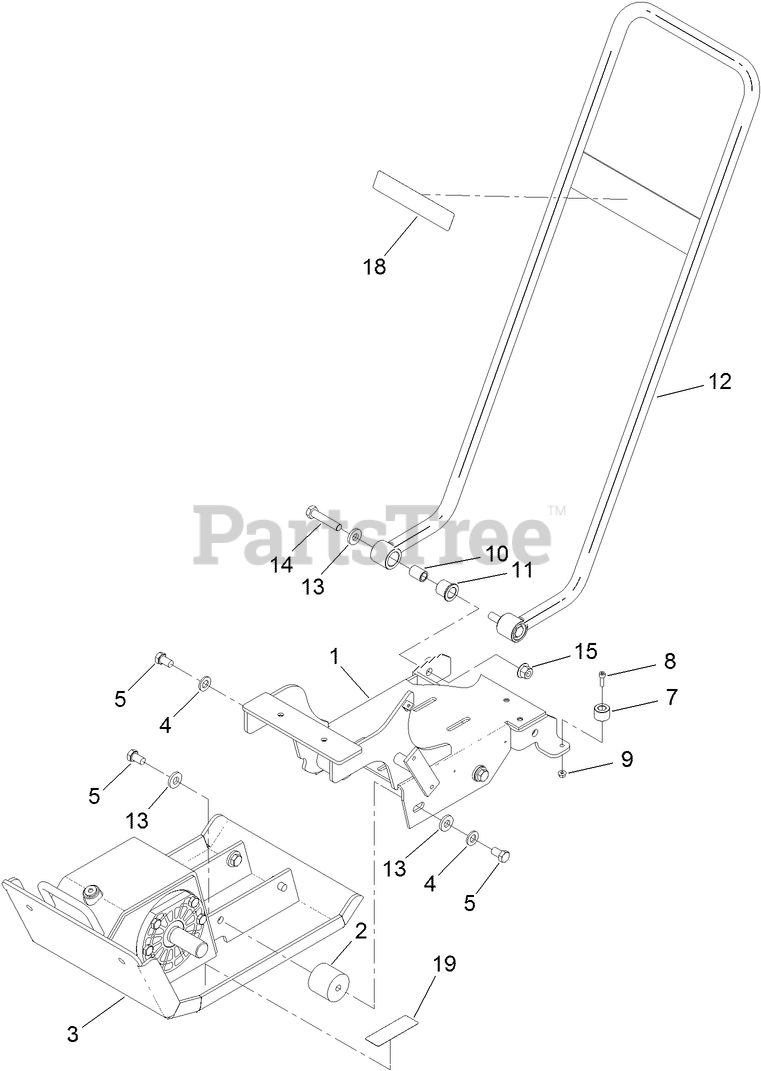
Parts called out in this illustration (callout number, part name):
1	DECK-ENGINE
2	MOUNT-SHOCK
3	BASE ASM
4	WASHER-FLAT
7	SPACER-STOP, HANDLE
9	NUT-HF
10	SPACER-HANDLE, PIVOT
11	BUSHING-HANDLE, MAIN PLATE
12	HANDLE-MAIN
13	WASHER-FLAT
14	SCREW-HH
15	NUT-LOCK, HHF
19	DECAL-WARNING
